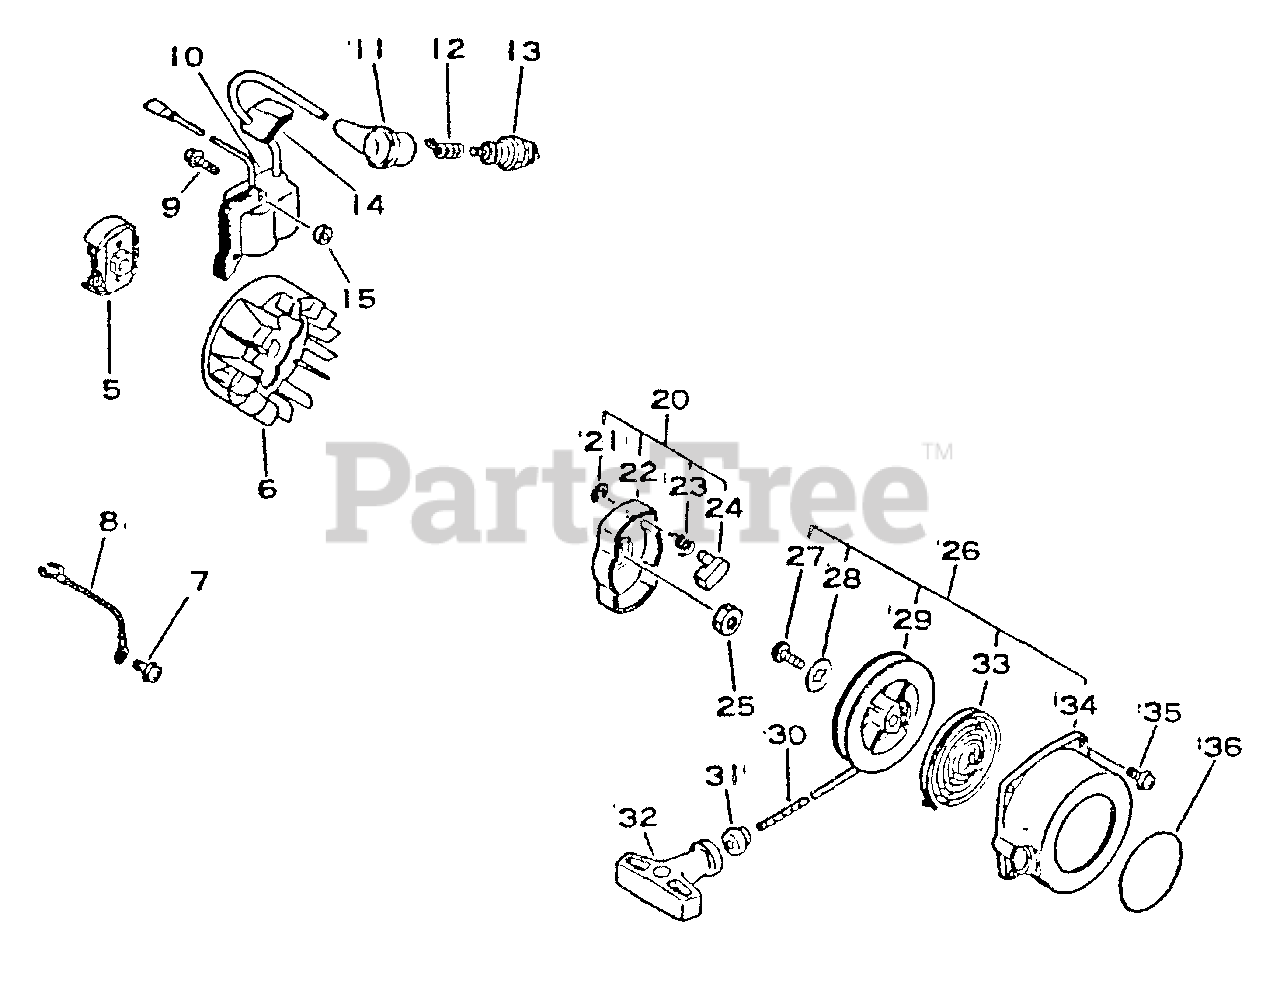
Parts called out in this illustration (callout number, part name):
5	CLUTCH ASSY
6	FLYWHEEL
7	SCREW - 5X10
8	LEAD - GROUND
9	SCREW - 4X22
10	COIL, IGNITION
11	CAP, SPARK PLUG
12	TERMINAL, SPARK PLUG CAP
13	SPARK PLUG -- BPM-7A
13	SPARK PLUG -- BPMR-7A
14	COVER, DUST
20	STARTER PAWL ASSY
21	RING, RETAINING - 6
22	CATCHER, PAWL
23	SPRING, RETURN
24	PAWL, STARTER
26	STARTER ASSY
28	WASHER
29	REEL, ROPE
30	ROPE, STARTER - 3X890
31	GUIDE, ROPE
32	GRIP, STARTER
33	SPRING, REWIND
34	CASE, STARTER
35	SCREW - 4X16
36	LABEL - ECHO
